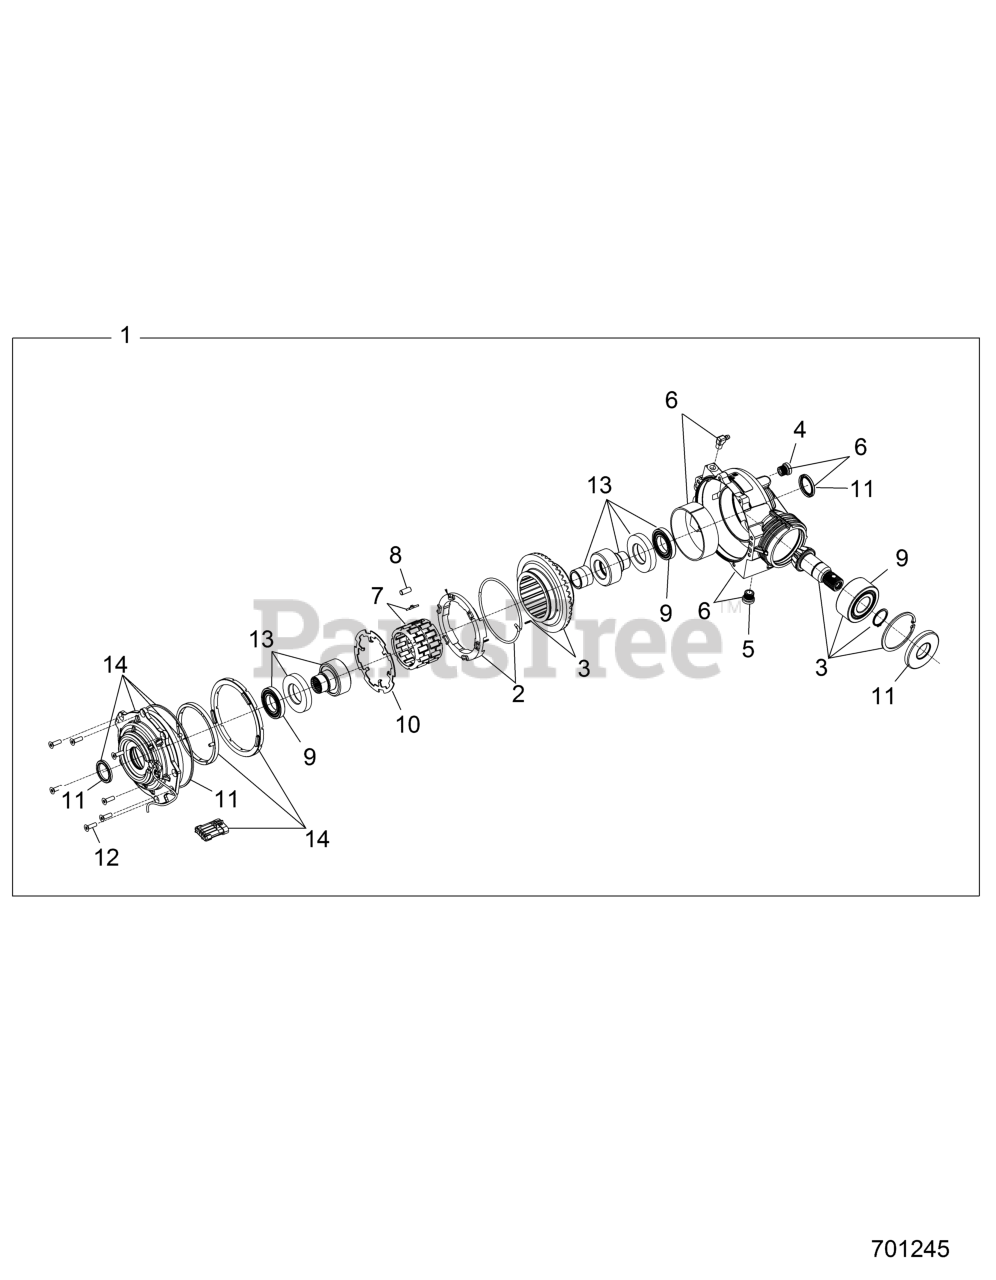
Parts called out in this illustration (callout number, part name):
1	ASM-GEARCASE,FRONT
2	K-TORSION SPRING & RETAINER
3	ASM. GEAR HOUSING AND PINION GEAR
4	FILL PLUG(1300-04-001-T)
5	DRAIN PLUG(6203-95-010)
6	KIT, GEARCASE ASSY
7	ASSY, ROLL CAGE ZN
8	K-CLUTCH ROLLS
9	BEARING-PINION,5306
10	PLATE-4WD ARMATURE
11	KIT-SEAL REPAIR
12	KIT-HUB,ASM
13	ASM-COVER,OUTPUT
14	KIT-FASTENER
